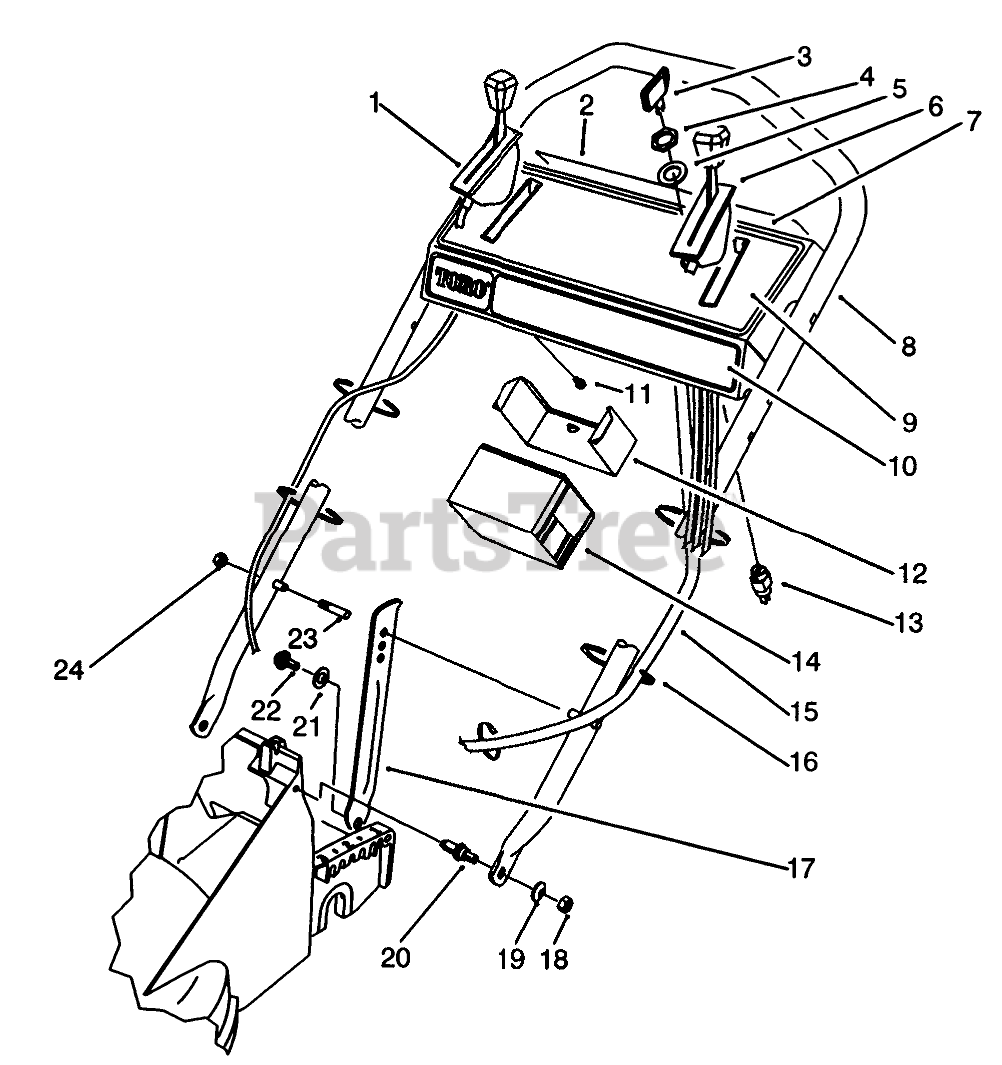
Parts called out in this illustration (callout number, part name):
1	Control-Ground Speed
2	DECAL - PANEL, REAR
3	KEY-IGNITION
4	NUT-HH
5	WASHER-TOOTH, INTERNAL
6	THROTTLE CONTROL
7	Panel-Control (Incl. Ref. #9)
8	HANDLE
9	DECAL - INSTRUCTION
10	DECAL - KEY LECTRIC
11	SCREW-HWHTF
12	Retainer-Battery
13	Switch-Starter (Incl. Ref #4 & 5)
14	BATTERY ASSEMBLY
15	Harness-Wire
16	TIE-CABLE
17	HANDLE LATCH
18	NUT-LOCK, NI
19	WASHER-PLAIN
20	SCREW - SHOULDER STUD
21	NYLON WASHER
22	SCREW-SHOULDER
23	HANDLE PIN
24	NUT-LOCK, NI
